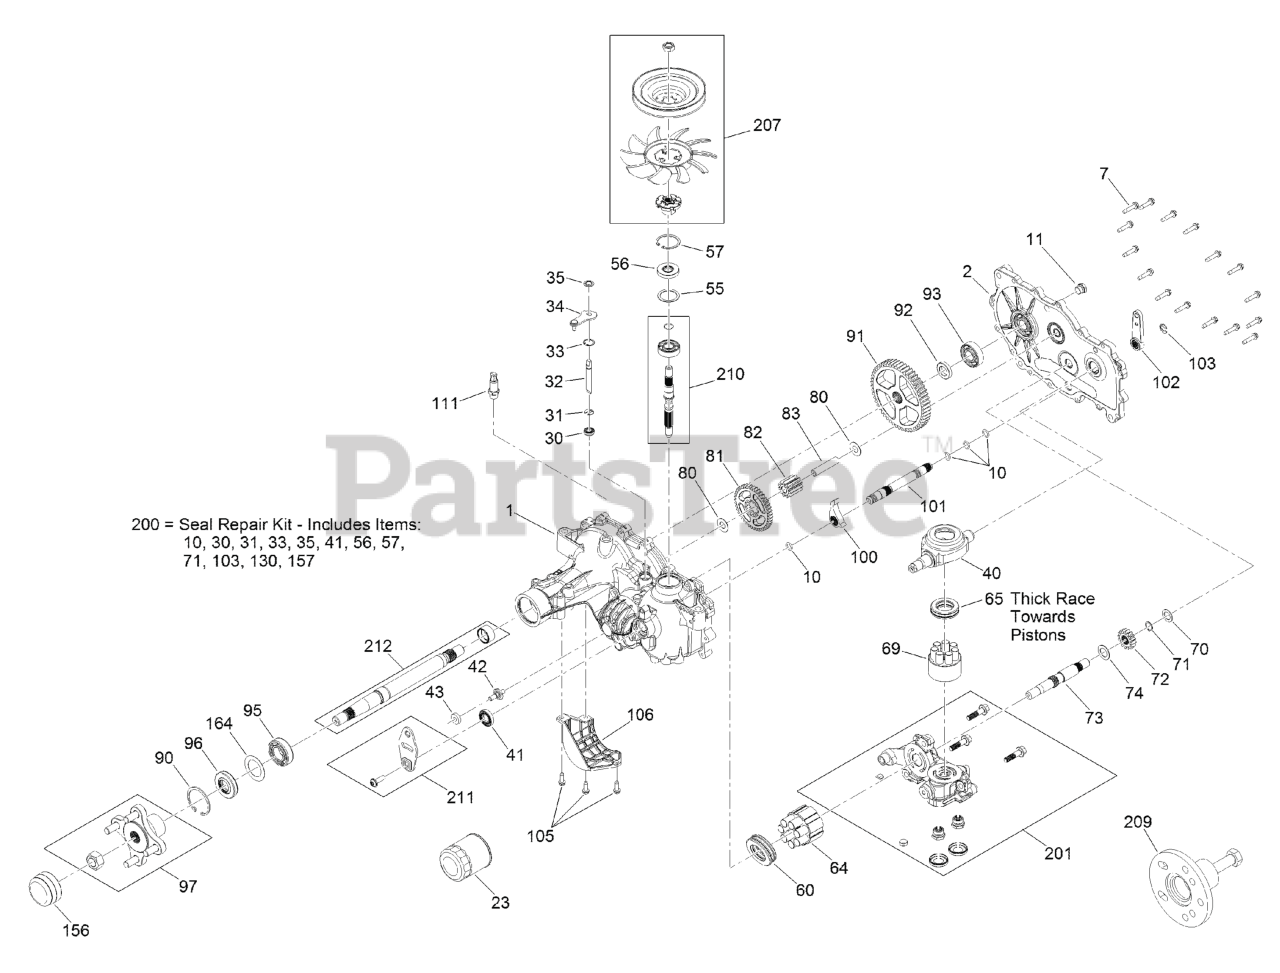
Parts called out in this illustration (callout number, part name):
1	MAIN HOUSING KIT
2	RH SIDE COVER KIT
7	SCREW-HHF
23	ELEMENT-OIL FILTER, HYD
30	SEAL-LIP
31	RING-RETAINING, EXTERNAL
32	ROD-BYPASS
33	RING-RETAINING, INTERNAL
35	RING-RETAINING, EXTERNAL
40	SWASHPLATE-TRUNNION
41	SEAL-LIP
43	PUCK-FRICTION
56	SEAL-LIP
57	RING-RETAINING
60	BEARING-THRUST
64	MOTOR CYLINDER BLOCK KIT
65	BEARING-THRUST
69	PUMP BLOCK ASM
70	WASHER-FLAT
71	RING-RETAINING
72	GEAR-16T
73	SHAFT-MOTOR
80	Washer
81	GEAR-43T
82	GEAR-11T
83	PIN-JACKSHAFT
90	RING-RETAINING
91	GEAR-54T
93	BEARING KIT
96	SEAL-LIP
97	HUB KIT
100	PAWL-BRAKE
101	SHAFT-BRAKE, INBOARD
102	HANDLE-BRAKE
103	RING-RETAINING, EXT
106	GUARD-FILTER, RH
111	ADAPTER-STRAIGHT
156	COVER-NUT, AXLE
200	SEAL KIT
201	RH CENTER SECTION KIT
207	FAN PULLEY KIT
210	INPUT SHAFT KIT
211	CONTROL ARM KIT
212	AXLE SHAFT KIT
